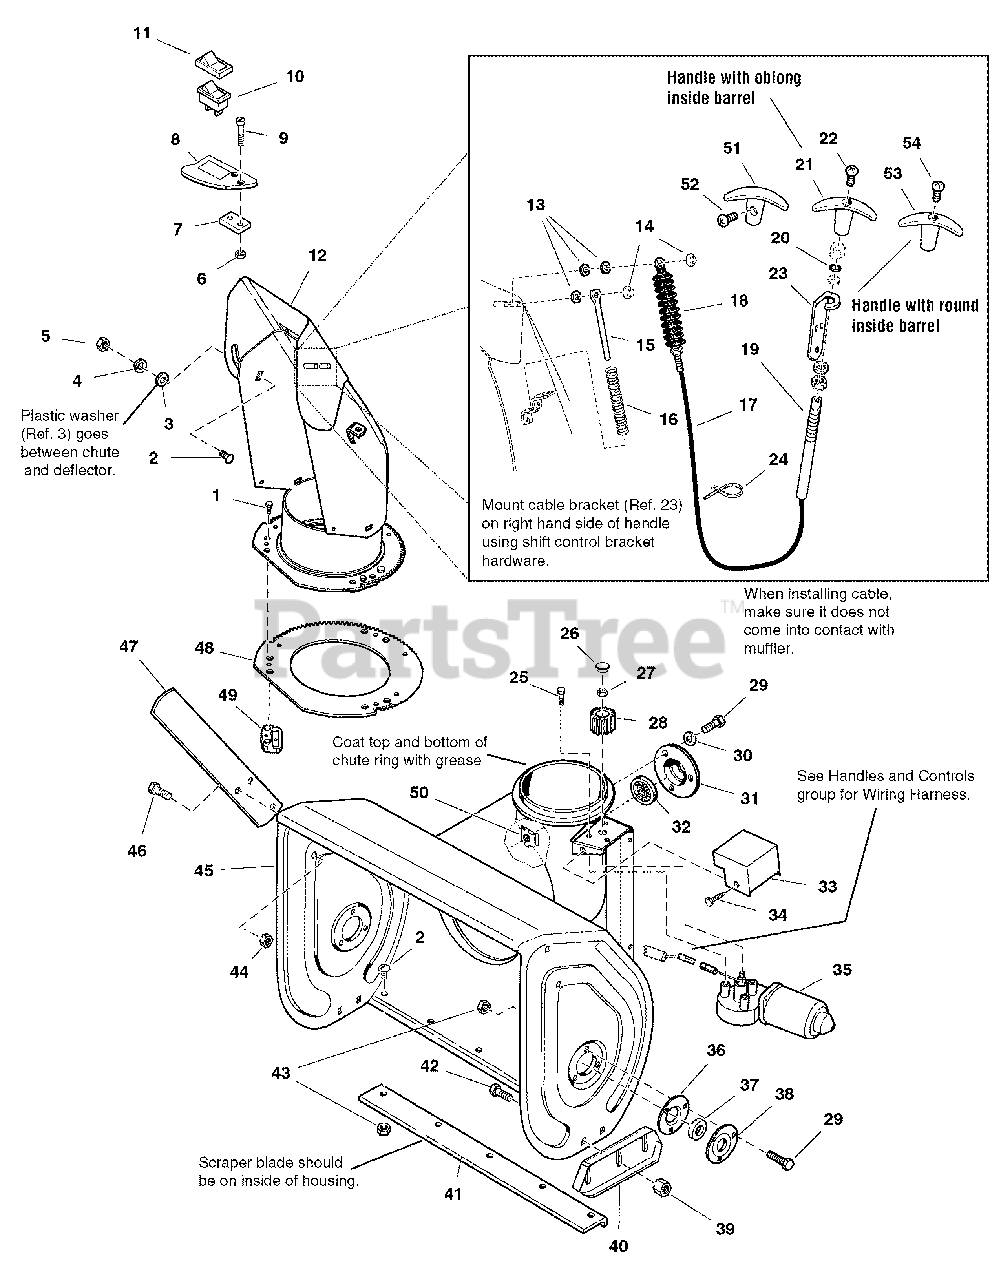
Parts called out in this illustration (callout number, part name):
1	SCREW, Hex Washer Head Pastite, 10-14 x 5/8
2	CARRIAGE BOLT, 5/16-18 x 3/4 G5
3	WASHER, Special, 97/250ID x 1-3/25OD x 3/100 Thick
4	WASHER, 5/16
5	NUT, Hex Lock ESNA Light, 5/16-18NC-3B
6	NUT, Hex Nylon 10-24
7	BRACKET, Mounting Switch Bottom
8	BRACKET, Mounting Switch Top
9	SCREW, 10-24 x 1.75
10	SWITCH, Rocker Chute
11	BOOT, Rocker Switch
12	CHUTE AND DEFLECTOR ASSEMBLY, Riveted, w/Pigtail
13	SPACER, Heat Treated
14	NUT, Push Pal, 1/4" Diameter Stud Capped
15	ROD, 5/16" Diameter, Spring Guide
16	SPRING, Complete
17	CABLE AND KNOB ASSEMBLY, Chute (Includes Ref. No. 18, 19, 20, 21 & 22)
18	BOOT, Bellows
19	COLLET
20	SEAL, Rod
21	KNOB
22	SCREW, 8-32
23	SUPPORT, Cable
24	TIE, Self Locking
25	SCREW, Hex Sems Washer, 1/4-20 x 7/8
26	CAPLUG, For 3/4" Hole
27	NUT, Hex KEPS, 1/4-20, Conical Washer
28	PINION, 1-3/20 LG
29	CAPSCREW, Hex Head, 5/16-18 x 5/8 G5
30	LOCKWASHER, Spring, 5/16
31	RETAINER, Bearing
32	BEARING, Ball
33	COVER, Pinion, 18GA
34	CAPSCREW, Hex Washer Head Taptite, 1/4-20 x 1/2
35	MOTOR, Electric 60" Mower Rocky
36	FLANGE, Bearing, w/Fitting
37	BEARING, Cartridge
38	FLANGE, Bearing, 3/8" Deep
39	NUT, Hex Flange, 3/8-16 ESNA
40	SKID SHOE, 7GA Formed, Heat Treated
41	BLADE, Scraper, 35-3/4 for 38"
42	CARRIAGE BOLT, 3/8-16 x 1 G5
43	NUT, Hex Flange, 5/16-18, Two-Way Lock GA
44	NUT, Hex Keps, 5/16-18, Conical Washer
45	HOUSING AND IMPELLER ASSEMBLY, 38"
46	CAPSCREW, Hex Head, 5/16-18 x 3/4 G5
47	CUTTER, Drift, 1/4" Thick, 20LG
48	HOLD DOWN, Chute
49	GEAR, Chute
50	NUT, Retainer Speed, 5/16-18
52	SCREW, Set, Hex #10-24 x 3/8
53	HANDLE "T"
54	SCREW, Round Head
